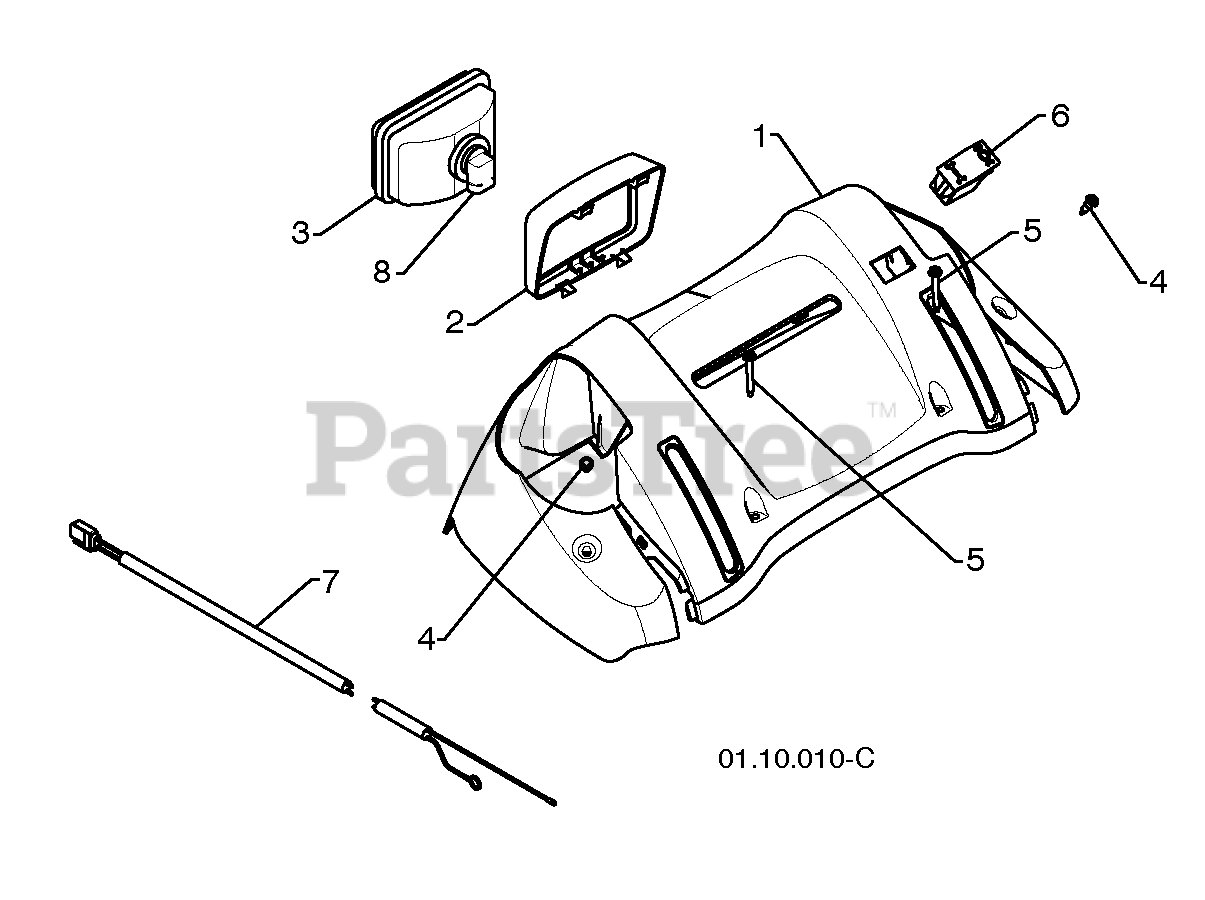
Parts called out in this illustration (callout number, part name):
1	CONSOLE PANEL GRAY
2	HEADLIGHT BEZEL GRAY
3	HALOGEN HEADLIGHT
4	SHOULDER SCREW 10-24 X .625
5	SCREW 10-24 X 1.25
6	GRIP SWITCH
7	WIRE HARNESS
